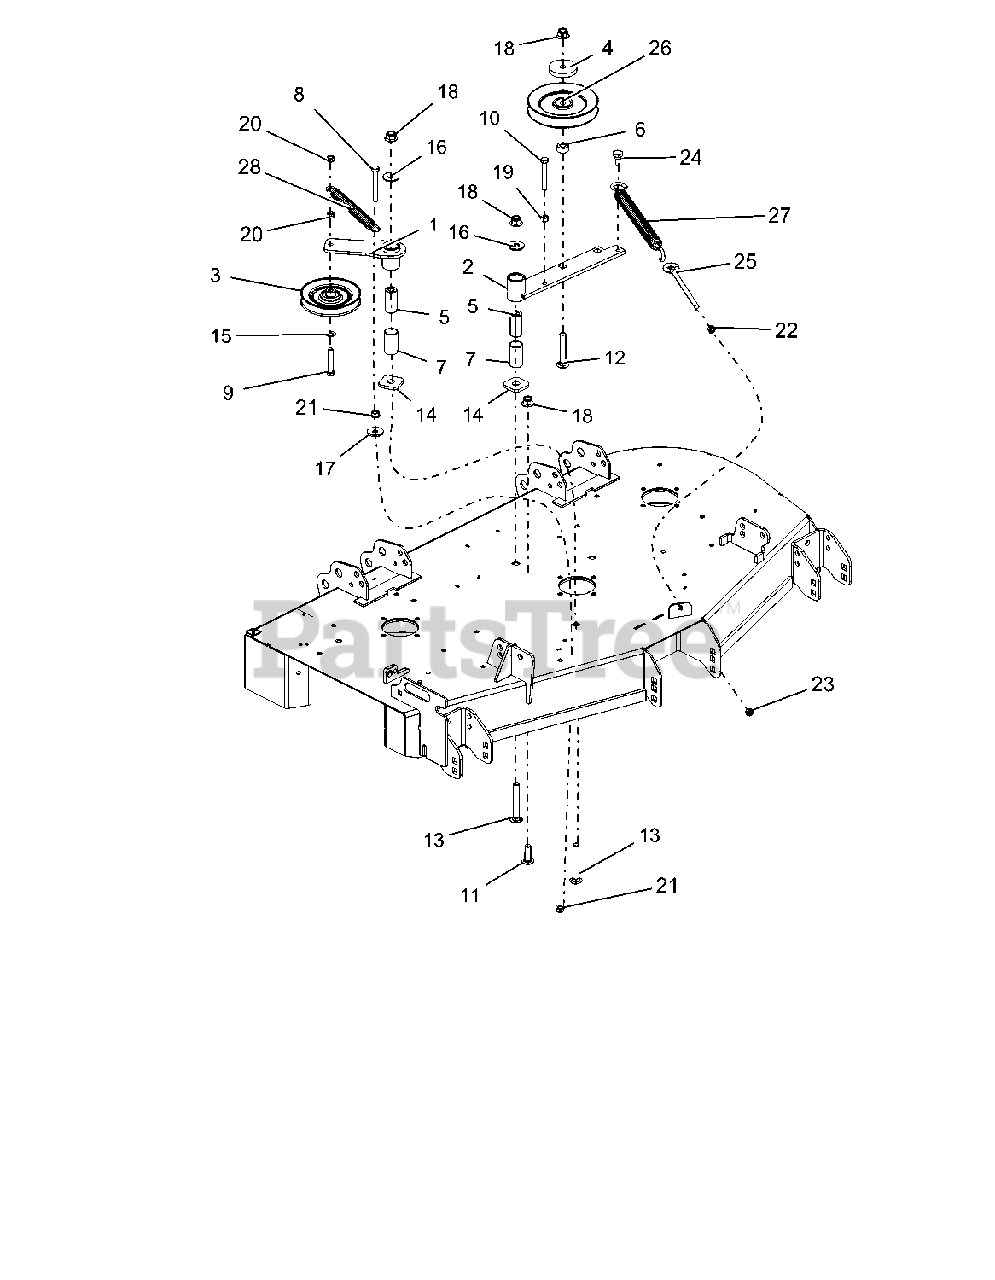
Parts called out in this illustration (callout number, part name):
1	WMT, IDLER PIVOT ARM-BLACK
2	WMT, IDLER PIVOT ARM-BLACK
3	IDLER, V-5.00" W/.69 STANDOFF
4	CAP, IDLER BEARING SEALING
5	BSHG, SPCR .502X.997X2.03
6	BSHG, SPCR .502 X .997.50 PM
7	BSHG, 1.00x1.125x1.947
8	BLT-HEX .38-16X3.00 GR5 YWZC
9	BLT-HEX .38-16X2.25 GR5 YWZC
10	BLT-HEX .38-16X2.75 GR8 YWZC
11	BLT-RDHDSQSHNK .50-13X1.50 YWZC
12	BLT-RDHDSQNK .50-13X3.00 G5 Y
13	BLT-RDHDSQNK .50-13X3.50 G5 Y
14	WSHR, -FLT.640X1.75X.250
15	WSHR-FL-STL.406X.812X.065 YWZ
16	WSHR-FL-STL.563X1.38X.109YWZC
17	WSHR-FL-STL .406X1.375X.135 YZ
18	NUT-LK-NYL-FLG .50-13 YWZC
19	NUT-HEX .38-16 YWZC
20	NUT-LK-CTR .38-16 YWZC
21	@NUT-SPNLK-FLG .375-16 YWZC
22	NUT, JAM .375-16 YWZC
23	NUT-LK-CTR-JAM .375-16 YWZC
24	BLT, SHLDR EP .38-16X.30 HEX YZ
25	BOLT, .38-16X6.00 .62 DIA EYE
26	SHEAVE, .50" ID X 6.00" OD V-IDLER
27	SPRG, EXTENSION
28	SPRG, EXTENSION .120X.845X6.55 WLD
